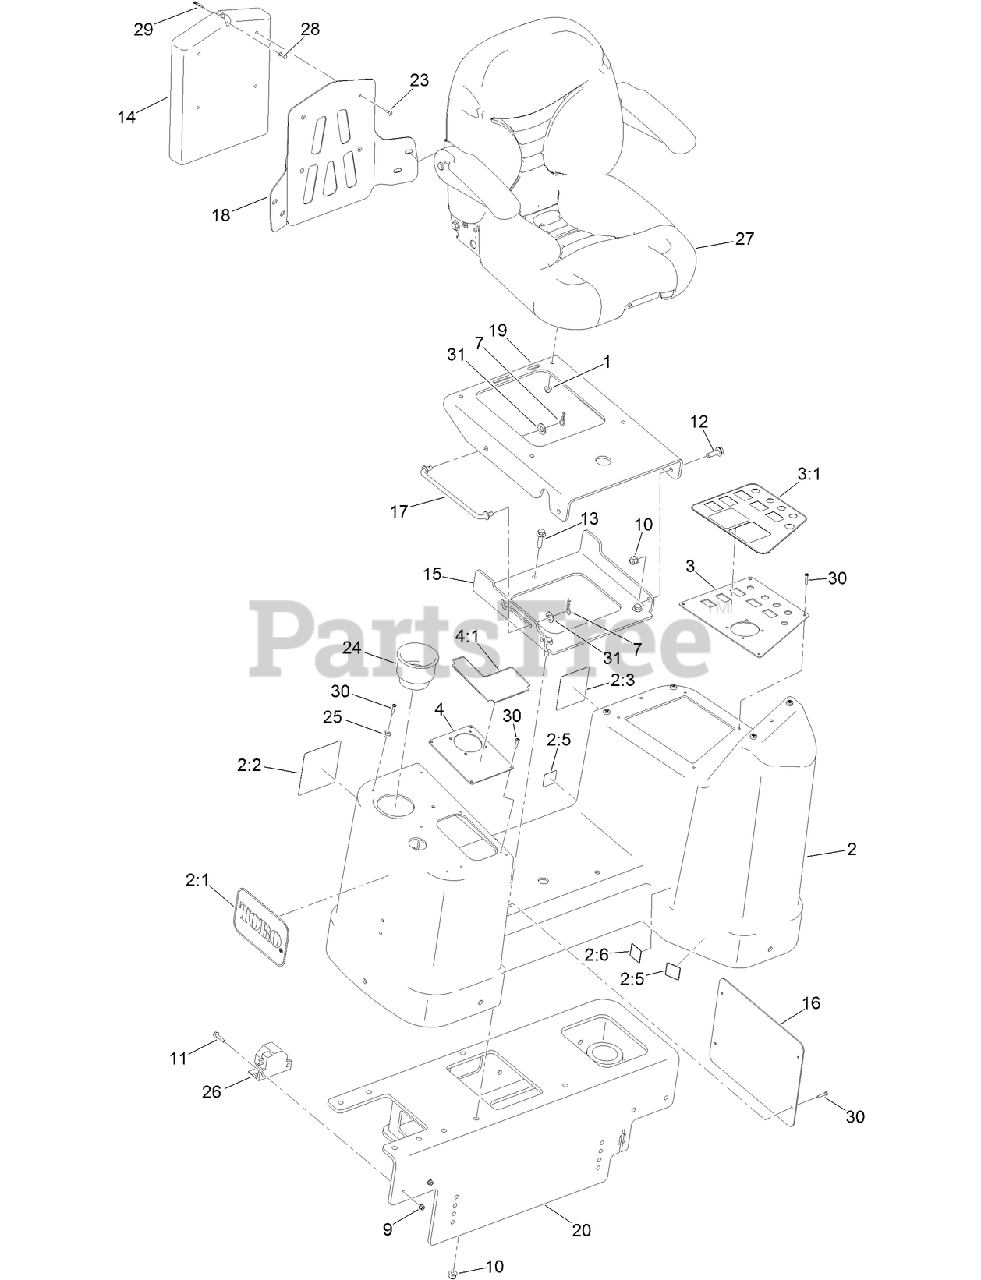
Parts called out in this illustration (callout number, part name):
1	NUT-HF, NI
2	OPERATOR CONSOLE ASM
2:1	DECAL
2:2	DECAL-SHOCK DANGER
2:3	DECAL-DANGER, NO RIDERS (FRONT)
2:5	DECAL-SEAT ADJUST
2:6	DECAL-SEAT SLIDE
3	SWITCH PLATE ASM
3:1	DECAL-JOYSTICK, LEFT
4	JOYSTICK MOUNTING PLATE ASM
4:1	DECAL-JOYSTICK, RIGHT
7	PIN-HAIR
9	NUT-FLANGE, NI
10	NUT-LOCK, NI
11	SCREW-HHF
12	SCREW-HHF
13	SCREW-HHF
14	HOLDER-MANUAL, OPERATOR
15	PLATE-SEAT MOUNT, BOTTOM
16	PLATE-SEAT, INSIDE PANEL
17	ROD-PROP, SEAT
18	PLATE-MOUNT, MANUAL
19	PLATE-SEAT MOUNT, TOP
20	CONSOLE-OPERATORS
23	RIVET-BLIND
24	CUP-HOLDER
25	GROMMET-RUBBER
26	ALARM-BACKUP
27	OPERATOR SEAT ASM (STATIC)
28	POST-MANUAL
29	LANYARD
30	SCREW-PPH
31	WASHER-FLAT
